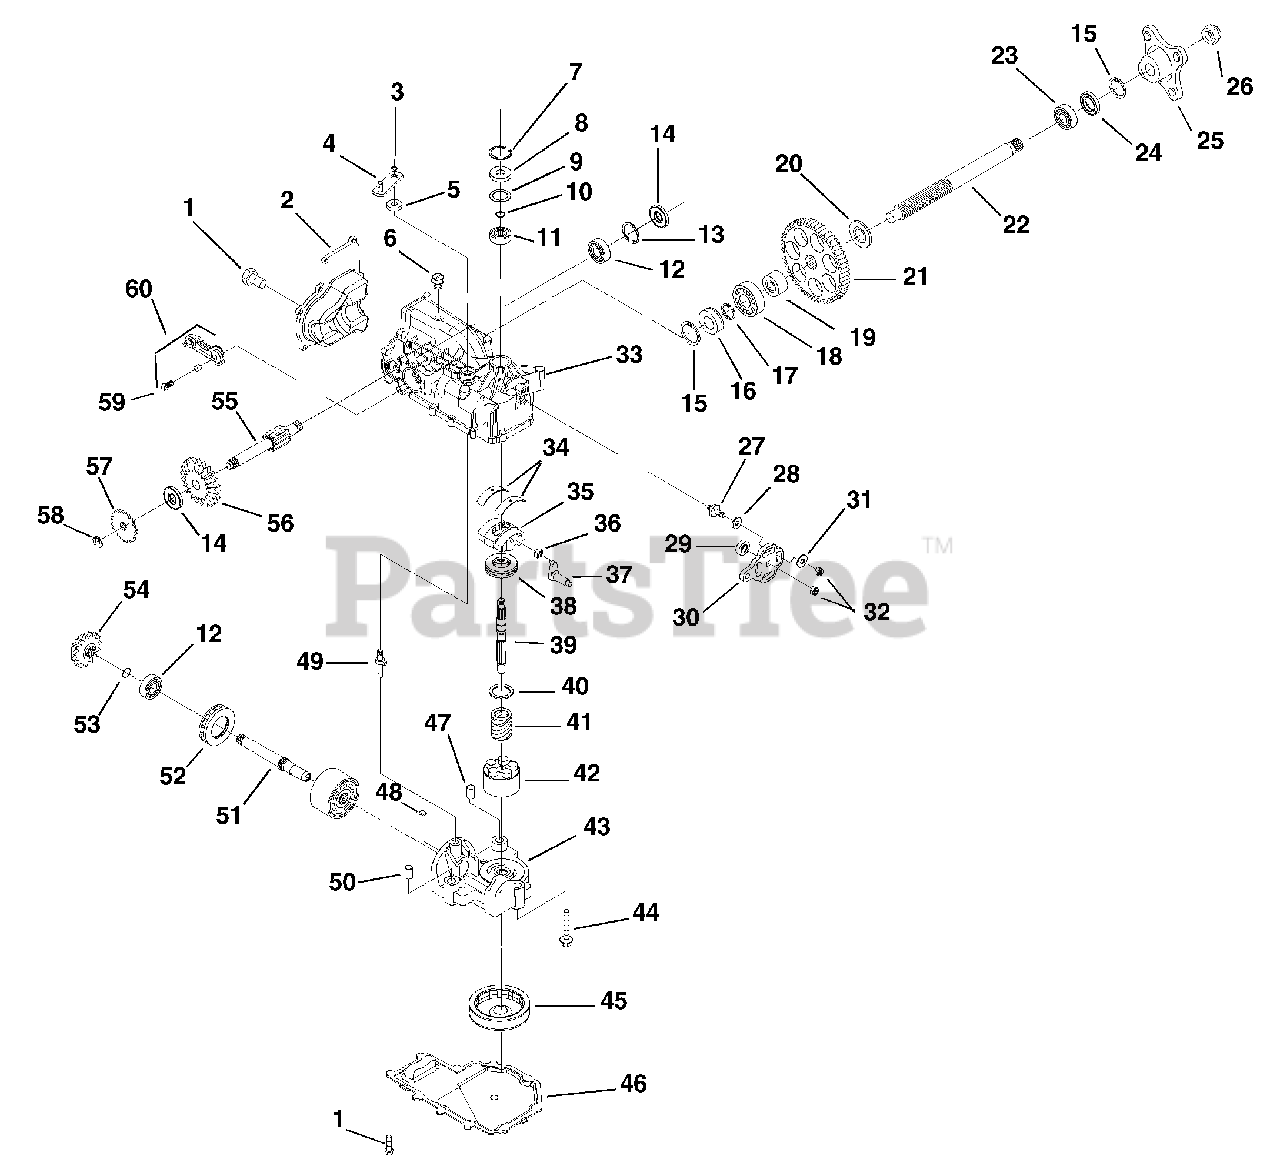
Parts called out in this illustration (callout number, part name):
2	COVER, END IZT
3	RING. RETAINING1
4	ARM. BYPASS
5	SEAL, LIP
6	Plug-Plastic
7	RING. RETAINING
8	SEAL, LIP 15X35X7
9	WASHER .98X1.37X.04
10	RING, WIRE RETAINING
11	BEARING, SHAFT BALL
12	BRG, BALL 17X40X12
13	RING, RET 1.56 INT
14	Seal-Brake Shaft
15	RING, RET 1.87 INT
16	PLUG, SEAL 1.86
17	RING, RET .75 EXT
18	BRG, BALL 20X47X14
19	Bushing-Axle
20	GEAR, SPUR 53T
21	Bushing-Axle
22	AXLE, 1.0X12.3
23	BRG, BALL 25X47X12
24	SEAL, LIP 25X47X7
25	Assembly-Hub
27	STUD. SHORT 5/16-24
28	PACK, FRICTION
29	Seal, Lip
30	Arm-Control
31	WASHER
32	NUT, HEX 5/16-24 NYLON
33	Assembly-Upper Housing
34	Bearing-Cradle
35	SWASHPLATE. VARIABLE
36	GUIDE. SLOT
37	ARM. TRUNNION TAPERED SQUARE
38	BEARING. THRUST 30 X 52 X 13
39	SHAFT, INPUT
40	WASHER. THRUST .59 X .79 X .04
41	SPRING. BLOCK
42	KIT, 10 CC BLOCK
43	Assembly-Center Section
44	HFHCS 3/8-24X2.5 (PATCH)
45	FILTER
46	HSG, IZT LOWER
47	PIN-HOLLOW .39X.5X1.
48	Bypass Plate
49	ACTUATOR, BYPASS
51	SHAFT, MOTOR
52	BRG, THRUST BALL 42X68X16
53	RING, RET WIRE .561 ID
54	GEAR, BEVEL 14T
55	Kit, Brake Shaft
56	GEAR, BEVEL 19T
57	BRAKE, PARK SPLINE
58	Ring-Retaining
59	HFHCS 1/4-20X.875
60	BRAKE ARM,RH IZT
